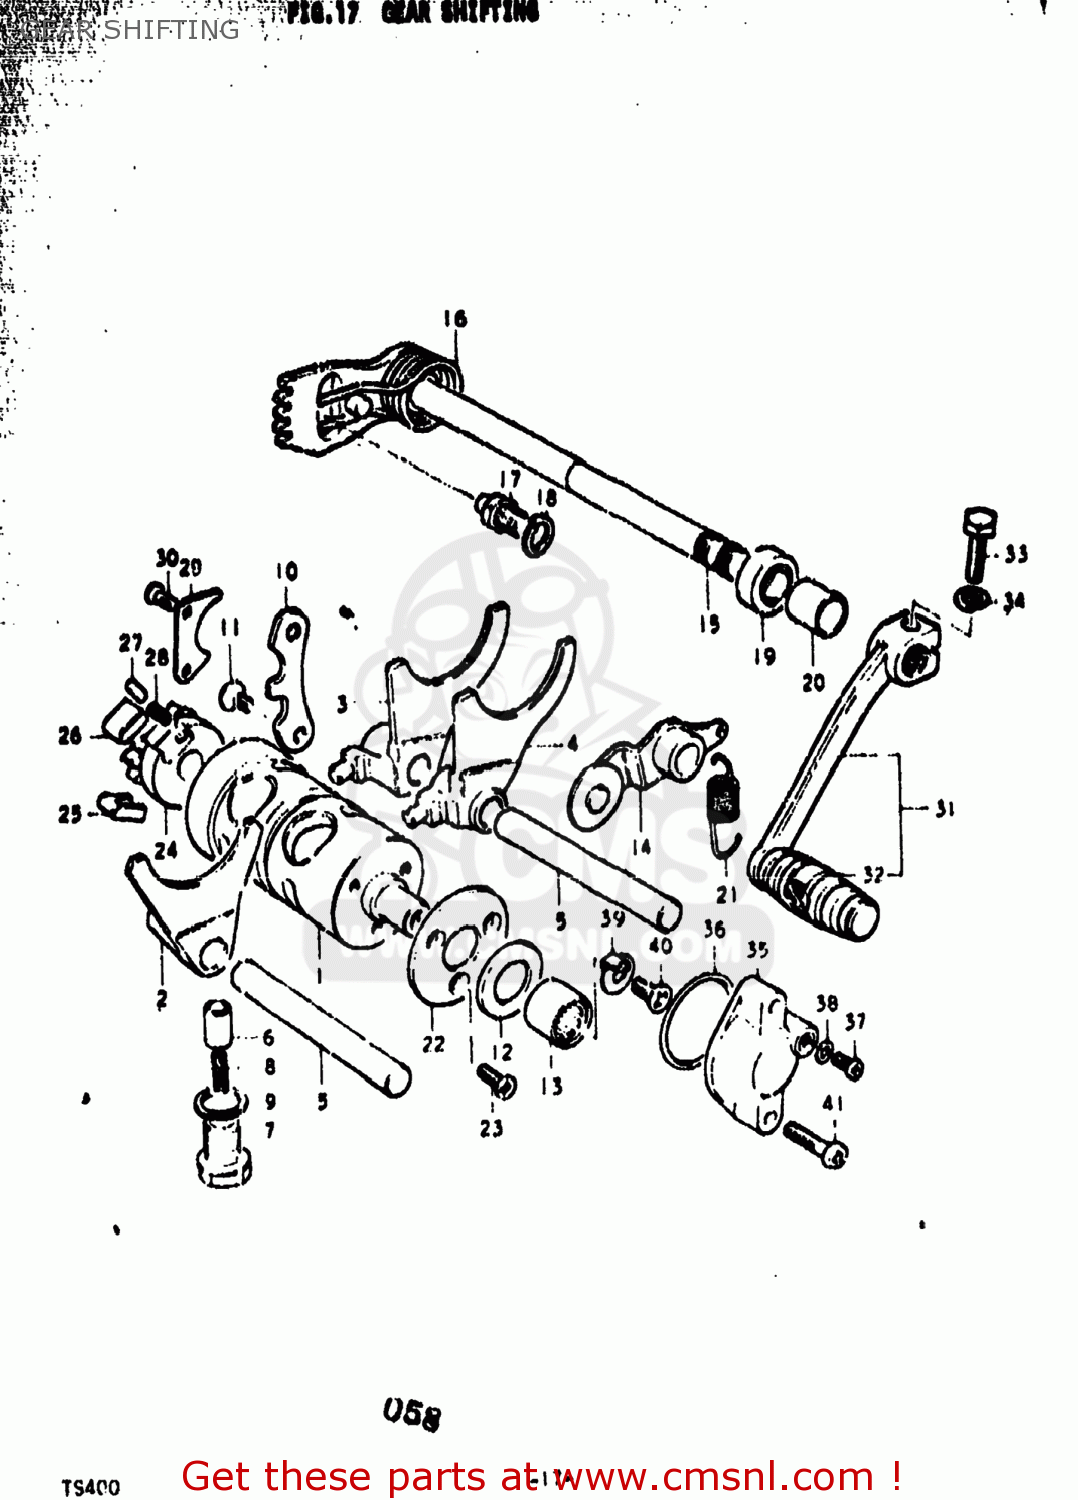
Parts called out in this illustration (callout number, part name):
1	CAM,GEAR SHIFT
2	FORK,GEAR SHIFT NO.1
3	FORK,GEAR SHIFT NO.2
4	FORK,GEAR SHIFT NO.3
5	SHAFT,GEAR SHIFT FORK
6	STOPPER,GEAR SHIFTING
7	BOLT,GEAR SHAFT CAM STOPPER
8	SPRING
9	GASKET(14X19.2X2) (NAS)
10	GUIDE,GEAR SHIFTING CABLE
11	SCREW
12	WASHER
13	ROLLER BEARING (12X18X1
14	STOPPER,GEAR SHIFTING
15	SHAFT,GEAR SHIFT
16	SPRING
17	STOPPER,GEAR SHIFT CAM
18	LOCK WASHER
19	OIL SEAL
20	CUSHION
21	SPRING
22	PLATE,GEAR SHIFT CAM
23	SCREW
24	RETAINER,GEAR SHIFT CAM
25	PAWL,GEAR SHIFT NO.1
26	PAWL,GEAR SHIFT NO.2
27	PIN(5X8)
28	SPRING
29	LIFTER,GEAR SHIFT PAWL
30	SCREW
31	LEVER ASSEMBLY,GEAR SHIFTING
32	RUBBER,GEAR SHIFT PEDAL
33	BOLT
34	LOCK WASHER
35	BODY,GEAR SHIFT SWITCH
36	O RING(D:1.9,ID:27.7)
37	SCREW
38	WASHER
39	CONTACT,GEAR SHIFT SWITCH
40	SCREW
41	SCREW
